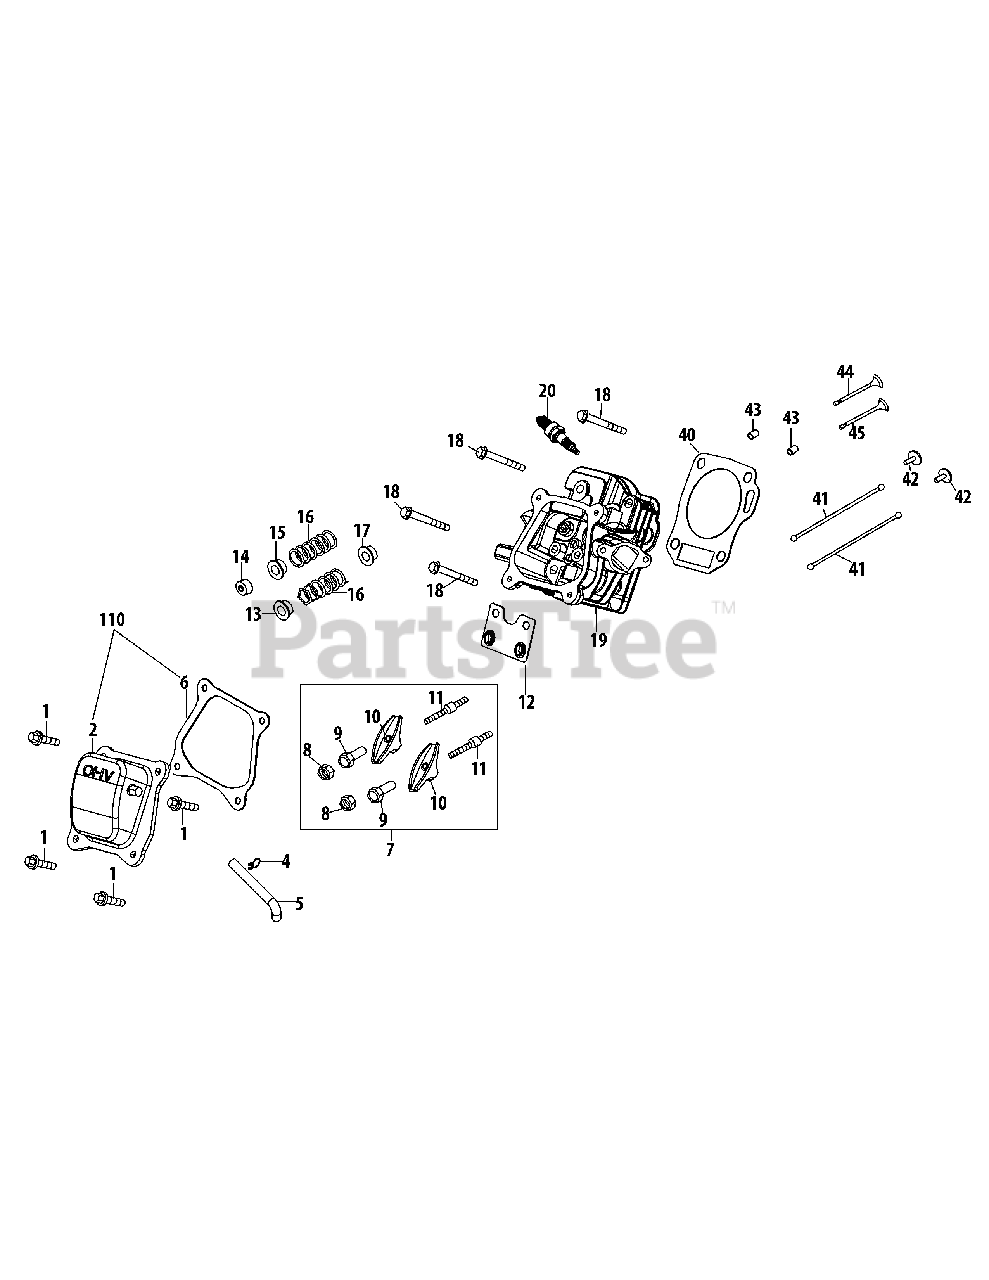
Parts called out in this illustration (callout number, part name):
1	Bolt M6×16
2	Valve Cover
4	Breather Hose Clamp
5	Breather Hose
6	Valve Cover Gasket
7	Rocker Arm Assembly
8	Nut, Pivot Locking
9	Adjusting Nut, Valve
10	Rocker Arm
11	Bolt, Pivot
12	Push Rod Guide
13	Retainer, Intake Valve Spring
14	Adjuster, Exhaust Valve
15	Retainer, Exhaust Valve Spring
16	Valve Spring
17	Intake Valve Seal
18	Bolt M8×55
19	Cylinder Head Assembly
20	Spark Plug
40	Gasket, Cylinder Head
41	Push Rod Kit
43	Dowel Pin 10×16
44	Exhaust Valve
45	Intake Valve
110	Valve Cover Kit
